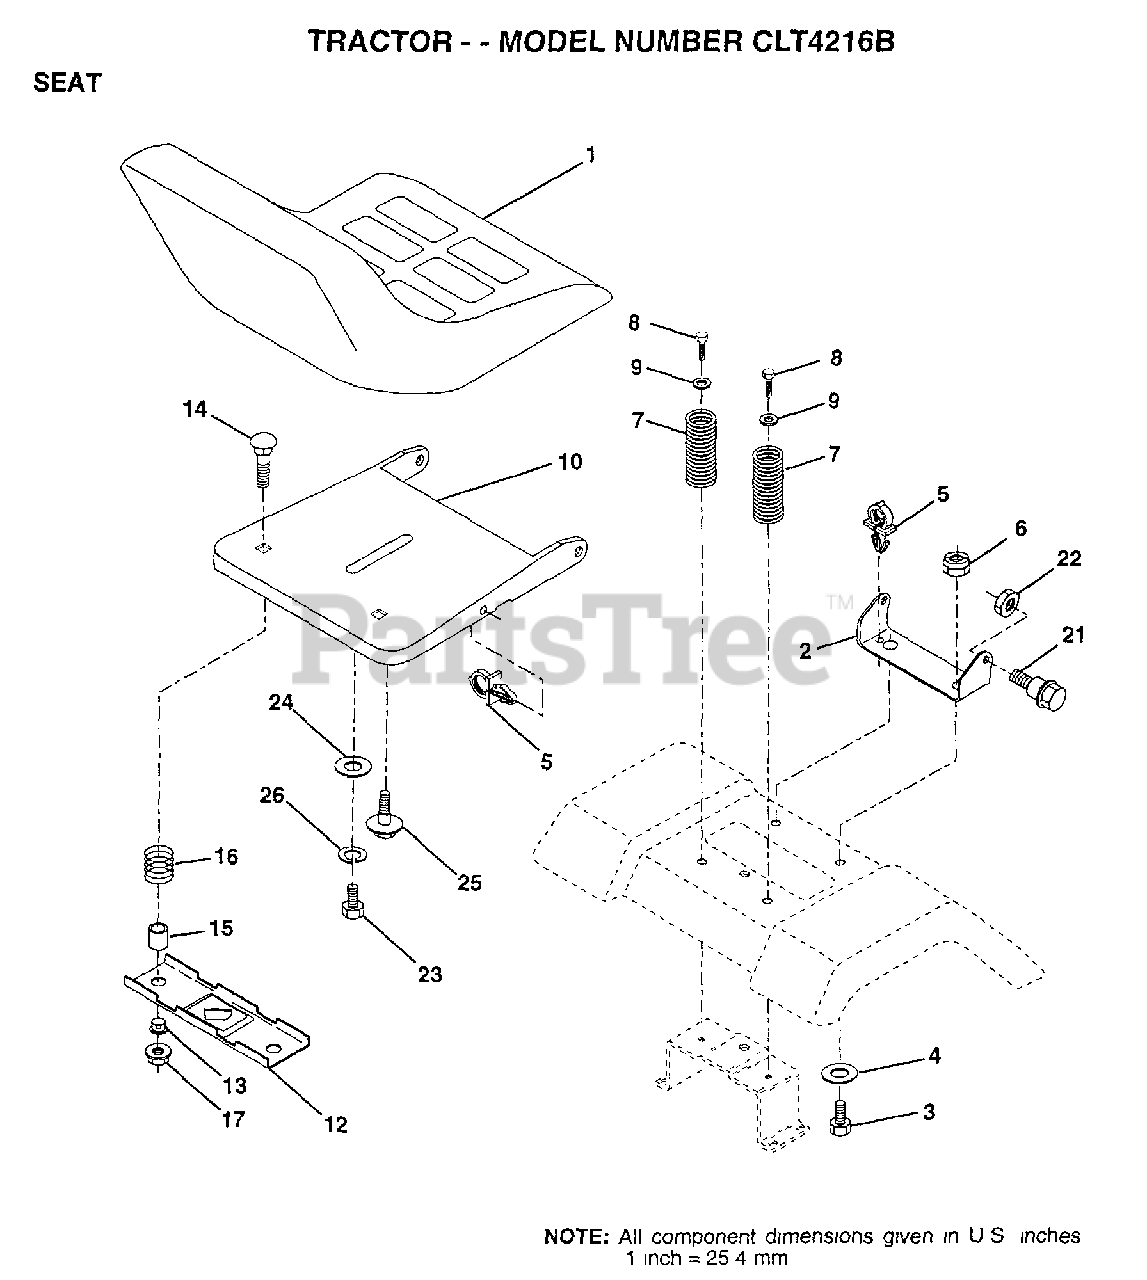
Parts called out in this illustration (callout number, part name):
1	SEAT
2	BRACKET PVT SEAT
3	BOLT
4	WASHER PM
5	CLIP.PUSH-IN.HING
6	NUT
7	SPRING COMPRESSIO
8	SCREW GTV
9	WASHER
12	BRKT SWITCH
13	BUSHING
15	SPLIT SPACER
16	SPRING
21	"BOLT,SHOULDER"
22	NUT
23	BOLT
24	WASHER
25	"BOLT,SHOULDER"
26	LOCKWASHER
